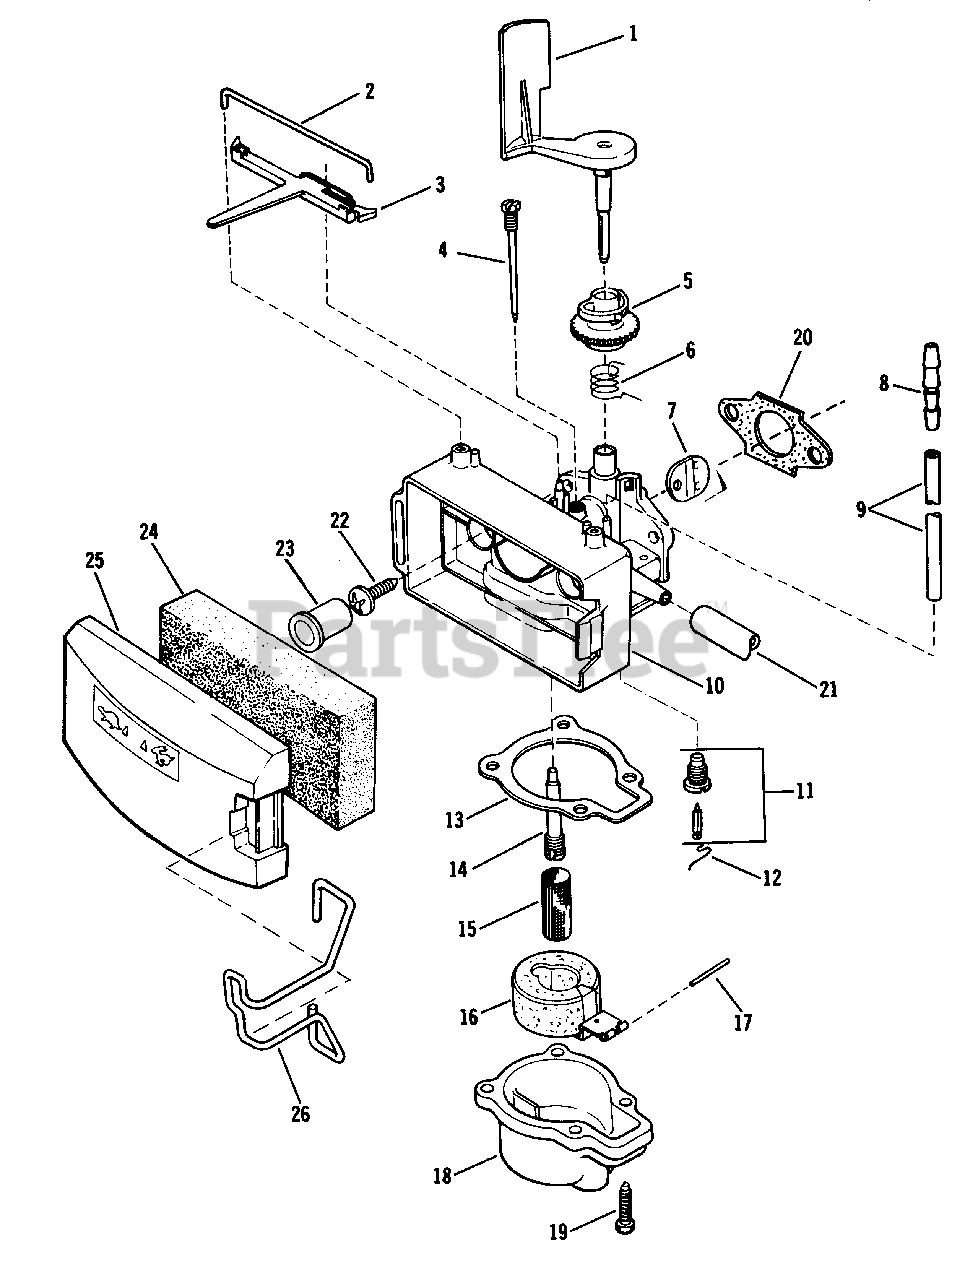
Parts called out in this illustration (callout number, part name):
1	Air Vane and Shaft
2	Retainer-Speed Control Lever
3	Speed Control Lever
4	Needle Adj. Assembly
5	Collar
6	Spring
7	Disc-Throttle
8	Connector-Reducer
9	Tube-Primer
10	Carburetor Body
11	Float Valve and Seat Assembly
12	Clip
13	Gasket
14	Nozzle
15	Filter-Carburetor
16	Float and Arm Assembly
17	Pin-Float
18	Float Chamber
19	Screw-Float Chamber
20	Gasket-Carb. to Crankcase Cover
21	Fuel Line
22	Screw-Carb. Mounting
23	Plug
24	Element-Air Filter
25	Cover-Air Filter
26	Retainer-Filter Cover
